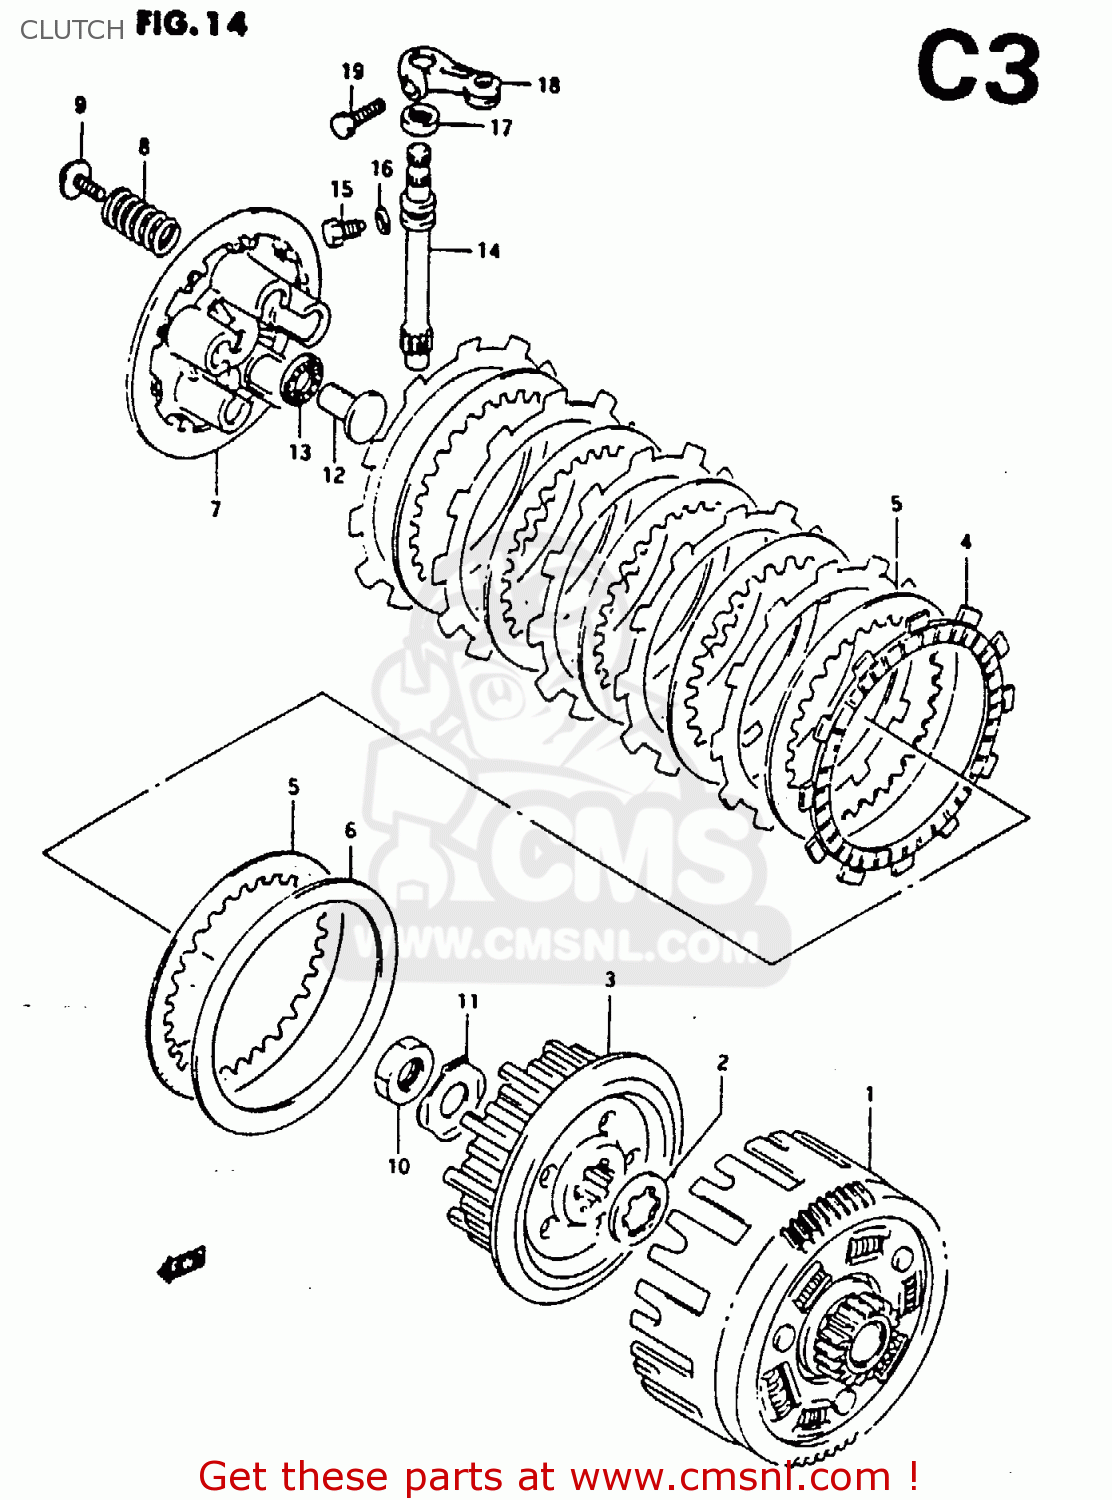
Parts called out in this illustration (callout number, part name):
1	GEAR ASSY,PRI DRIVEN
2	WASHER
3	HUB,CLUTCH SLEEVE
4	PLATE,CLUTCH DRIVE(T:3.0) (NAS)
5	PLATE,CLUTCH DRIVEN(T:2.0) (NAS)
6	SEAT,WAVE WASHER
7	DISC,CLUTCH PRESSURE
8	SPRING
9	BOLT 5X16
10	NUT
11	WASHER
12	RACK,CLUTCH RELEASE
13	BEARING(10X22X2.8)
14	PINION,CLUTCH RELEASE
15	BOLT(6X12)
16	WASHER
17	SEAL,OIL(10X17X5)
18	ARM,CLUTCH RELEASE
19	BOLT
